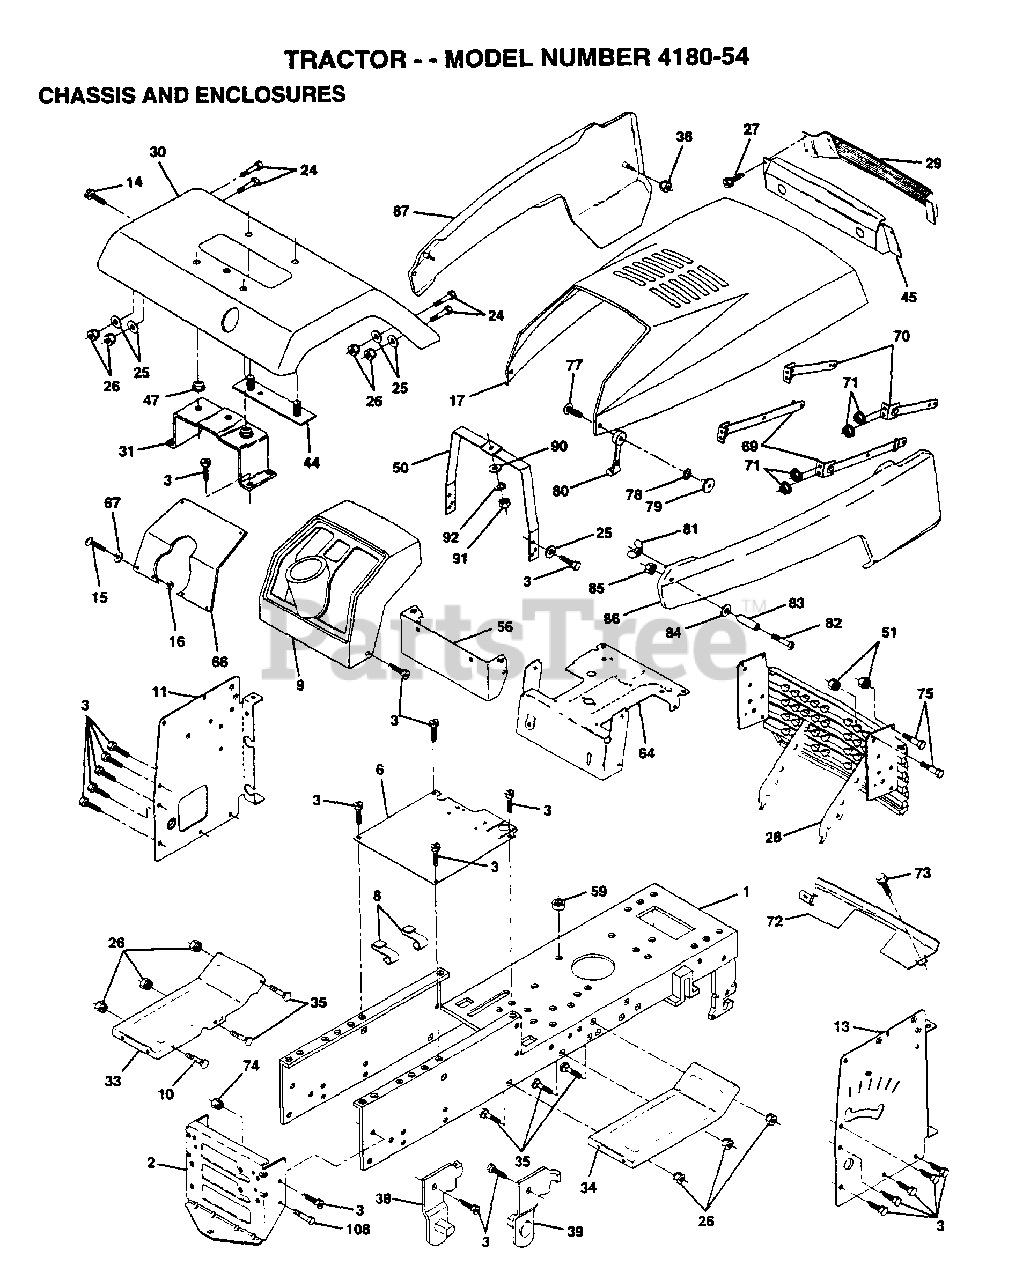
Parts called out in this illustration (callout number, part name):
1	CHASSIS.WLD.11GA
2	DRAW BAR
3	SCREW
8	"CLIP,INSULATOR"
9	DASHBOARD BLACK
11	PANEL.DASH.LH.PNT
13	PANEL.DASH.RH.PNT
14	SCREW LT
15	SCREW
24	BOLT
25	WASHER
26	NUT
29	LENS.BAR.CLEAR
31	BRKT.ASM.FENDER
33	FOOTREST.LH.LT/GT
34	FOOTREST.RH.LT/GT
35	BOLT
36	PAL NUT LT
38	BRACKET ASM LH
39	BRACKET ASM RH
44	STRAP ASM FENDER
47	NUT-PUSH YT
50	DASH.SUPT.YP/HUSQ
56	DASH.EXT.PNT.
66	PLATE SLKSCR YP
67	WASHER
71	NUT HXKEP 1/4X20
72	STRAP.GRILLE.424
73	SCREW CRT
77	SCREW
78	LOCKWASHER
79	WELDNUT
80	HOOD LATCH T
82	SCREW
83	SPACER LT
84	WASHER
87	PANEL SIDE LH
90	WASHER PM
92	LOCKWASHER
